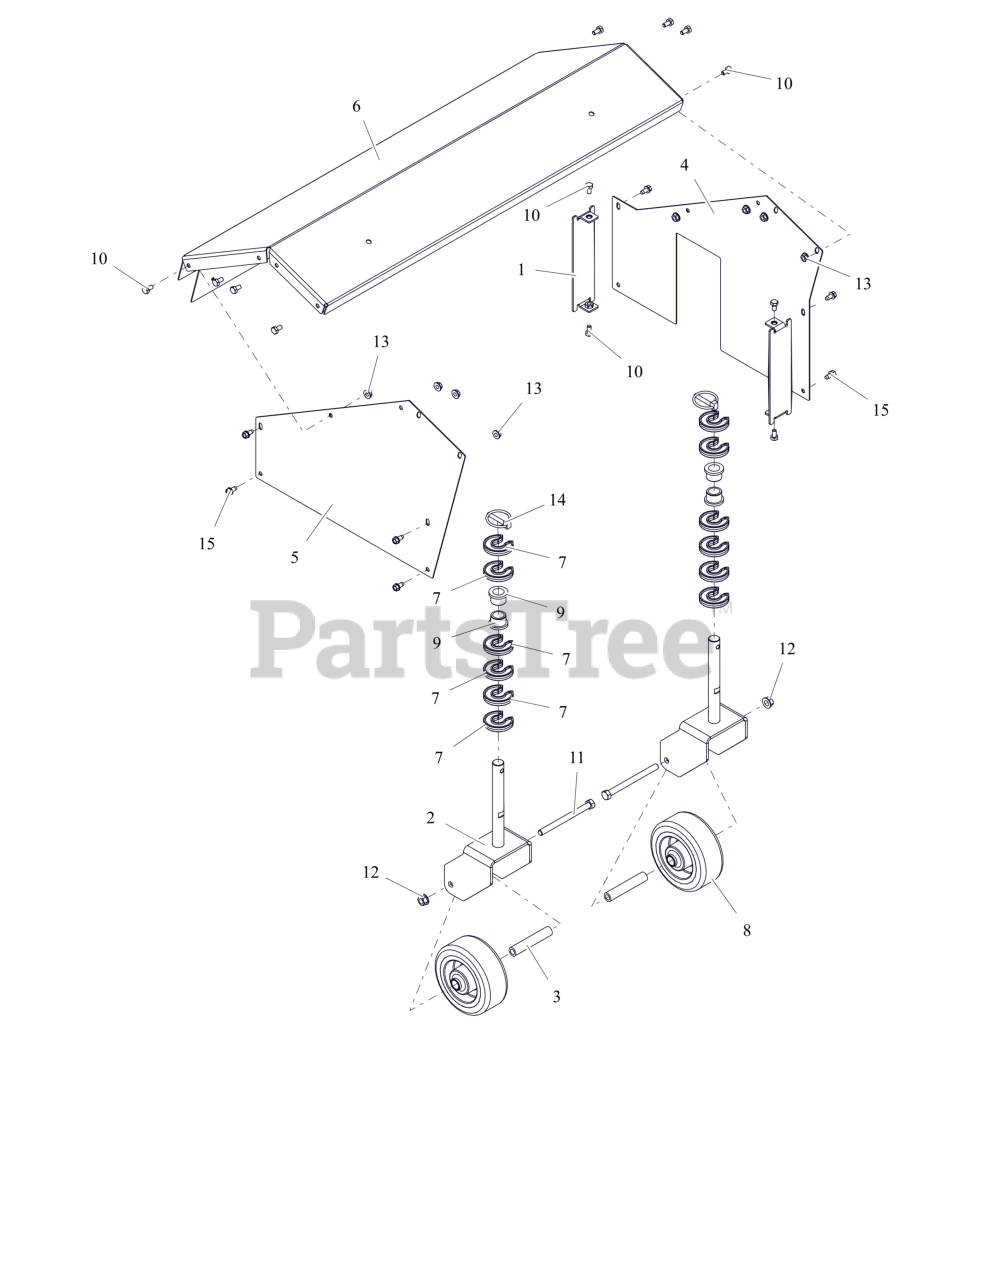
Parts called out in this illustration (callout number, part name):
1	COVER,END
2	FRAME, CASTER (BLACK)
3	SPACER, CASTER WHEEL
4	COVER,LH SIDE BRUSH
5	COVER,RH SIDE BRUSH
6	COVER, BRUSH PB W/DECALS
7	CLIP-HOC FIXED
8	WHEEL, CASTER - 5"OD
9	BUSHING, FLANGE .75X.75X1.0
10	BLT,HEX .25-20X.50 G5 ZCC
11	BLT, HEX 0.375-16X4.5 GR5 ZCC
12	NUT-LK-TOP-FLG .38-16 ZC120
13	NUT-LK-TOP-FLG .250-20 GF ZCC
14	PIN, LYNCH .25X1.562 ZCC
15	SCR-TAP .25-20X.50 HWH ZCC
